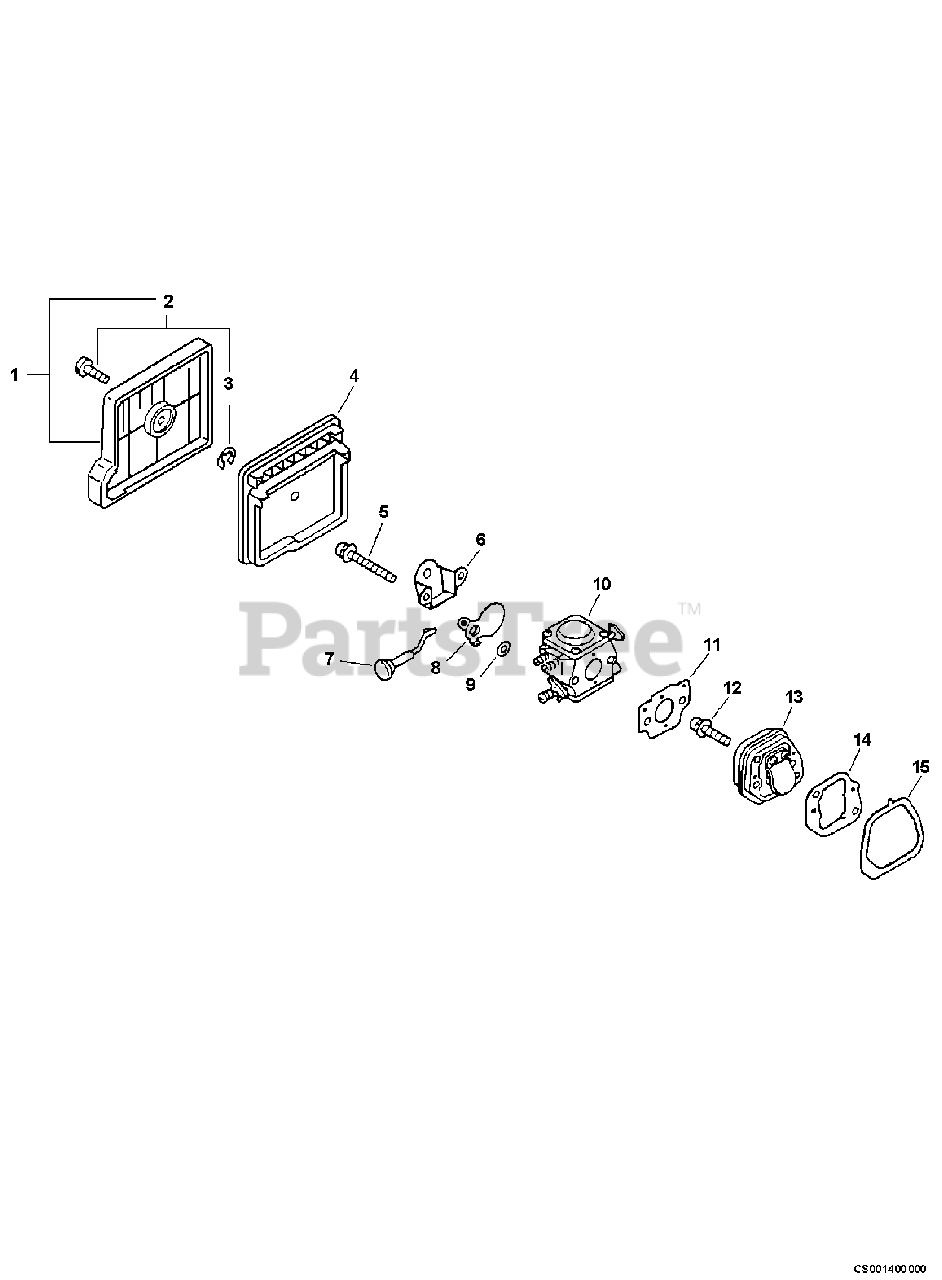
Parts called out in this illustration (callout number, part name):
1	COVER ASSY, AIR FILTER
2	THUMBSCREW
3	E-RING 4
4	FILTER, AIR
5	SCREW 5×45
6	PLATE, PREVENT
7	ROD, CHOKE
8	SHUTTER, CHOKE
9	WASHER 5.5×8×0.8
10	CARBURETOR - WT-589
11	GASKET, INTAKE
12	SCREW 5×18
13	INSULATOR KIT
14	GASKET, INTAKE
15	SEAL, INTAKE
